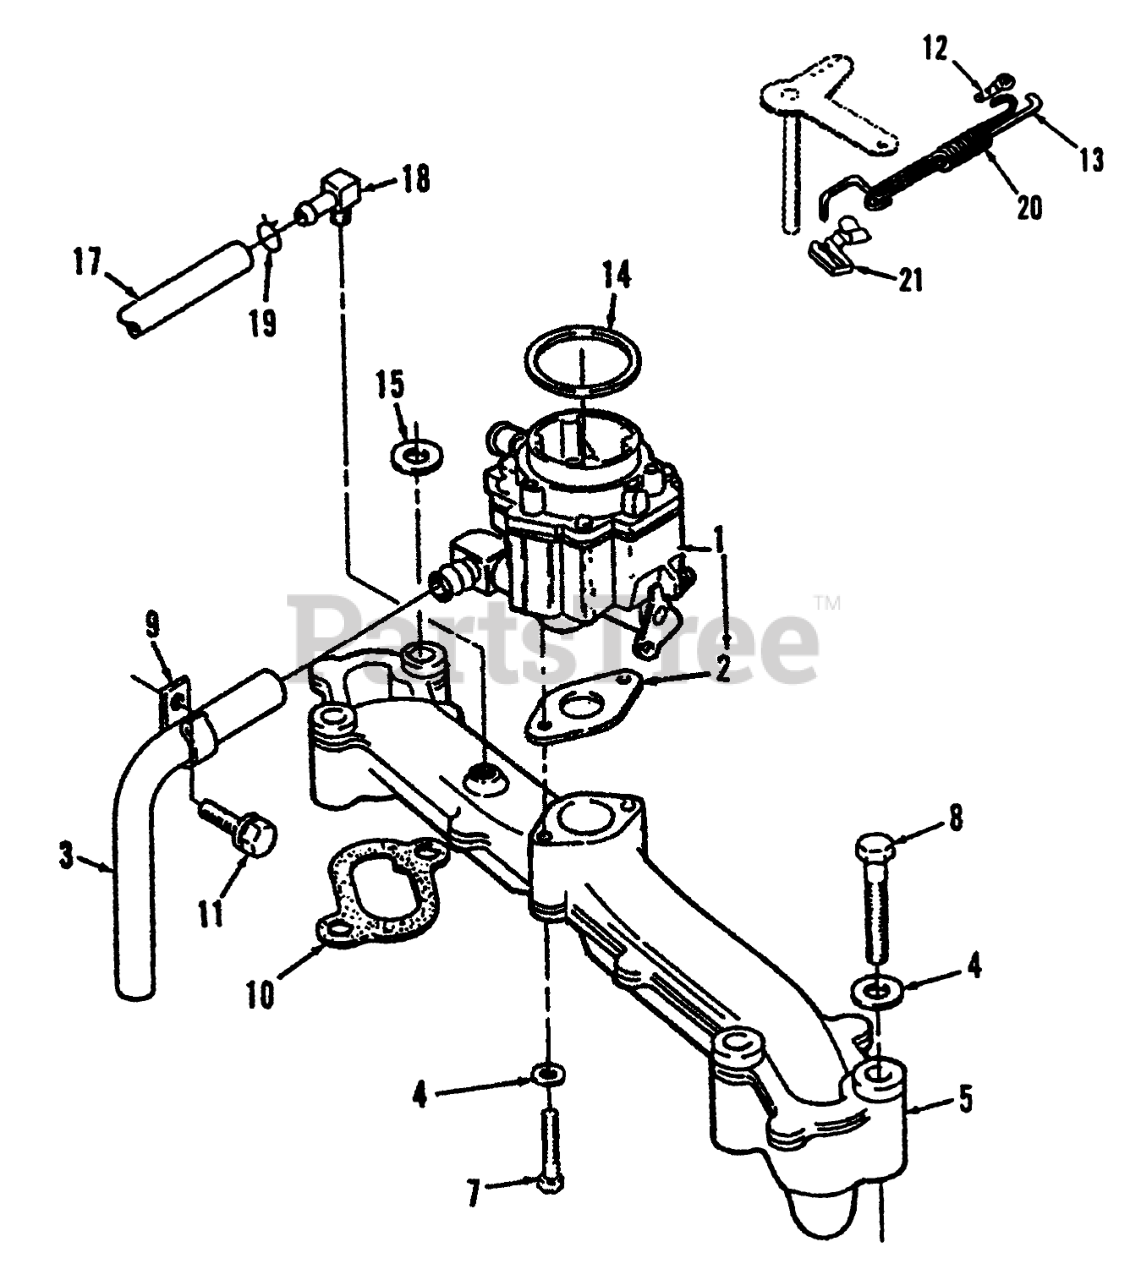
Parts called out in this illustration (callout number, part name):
1	Carburetor-Complete (Includes Mounting Gasket, Elbow, & 0-Ring) (See Separate Page for Components)
2	Gasket
4	WASHER-FLAT
5	Intake Manifold
7	Bolt
9	Clip
10	GASKET
11	SCREW-HWH
12	Retaining Clip
13	Governor Control Rod
15	FLAT WASHER
16	FLAT WASHER
17	HOSE-RUBBER, BREATHER
18	FITTING-BARB
19	CLAMP-HOSE
20	Spring-Governor Rod
21	Clip-Retaining
